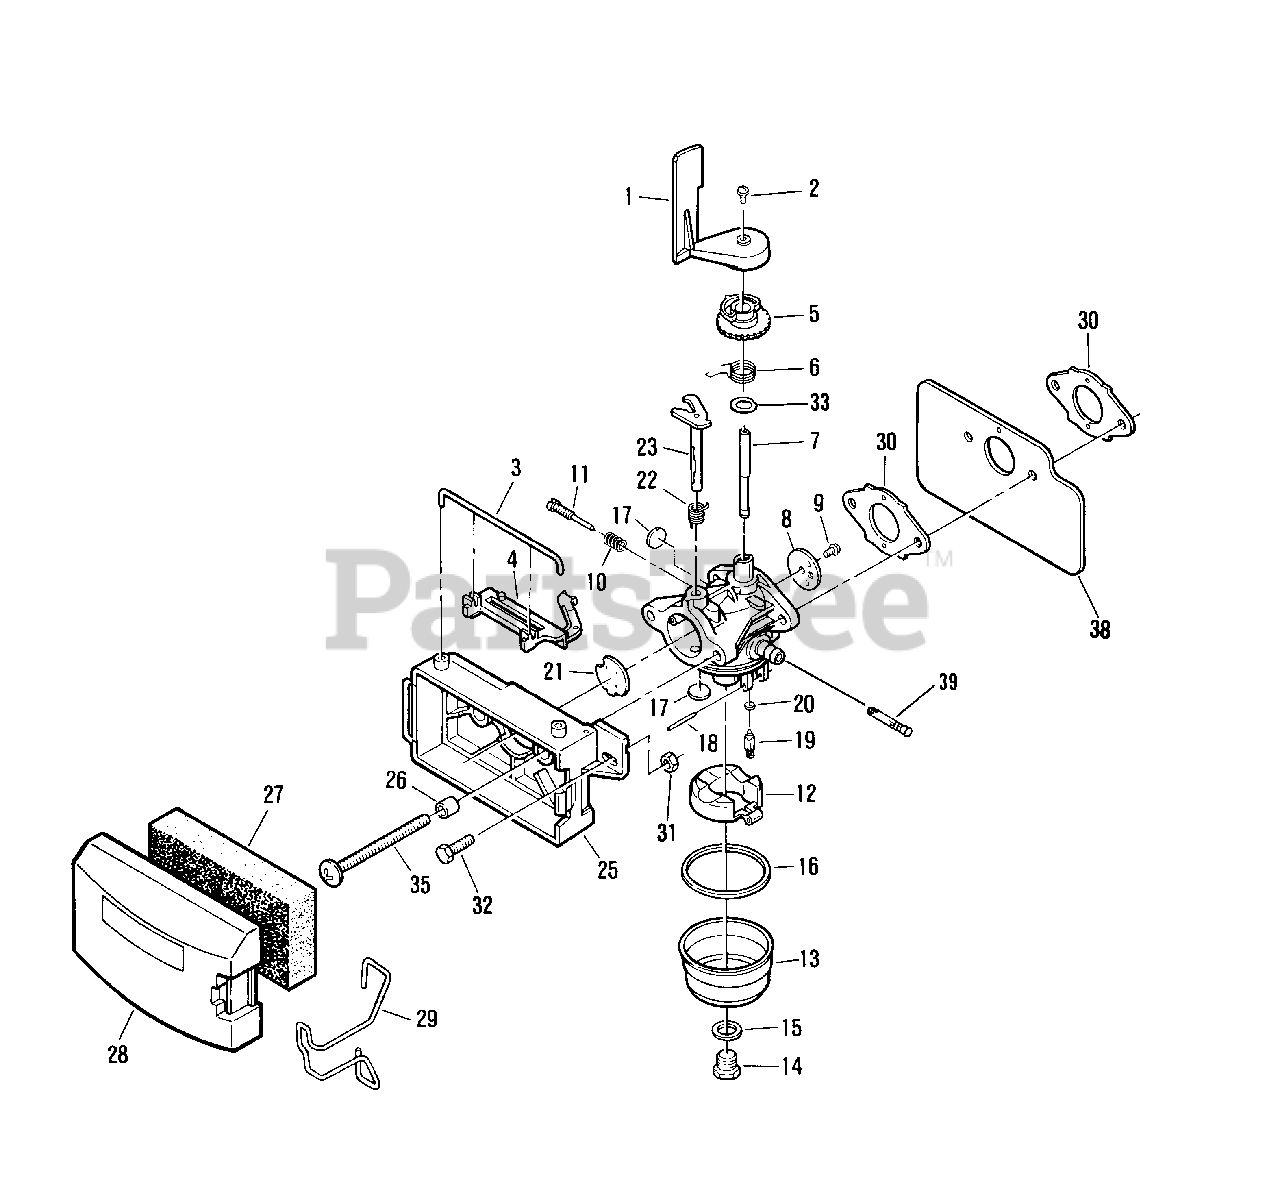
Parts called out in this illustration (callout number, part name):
1	Air Vane
2	Screw-Air Valve
3	Retainer-Speed Control Lever
4	Control Lever-Governor
7	Shaft-Throttle
8	Valve-Throttle
9	Screw-Throttle Valve
10	Spring-Idle Needle
11	Needle-Idle
12	Kit-Float Assembly
13	Bowl-Fuel
14	Screw-Bowl Retainer
15	Gasket-Bowl Retainer
16	Gasket-Fuel Bowl
17	Plug-Welch
18	Shaft-Float
19	Valve-Inlet Needle
20	Seat-Valve
21	Valve-Choke
22	Spring-Choke Return
23	Shaft-Choke
25	Base-Air Filter
26	Spacer-Air Filter Base
27	Element-Air Filter
28	Cover-Air Filter
29	Retainer-Air Filter Cover
30	Gasket-Carburetor to Crankcase Cover
31	Nut-Hex (Throttle Cable)
32	Screw (Throttle Cable)
35	Screw-Carburetor Mounting
38	Heat Shield
39	Fuel Filter
